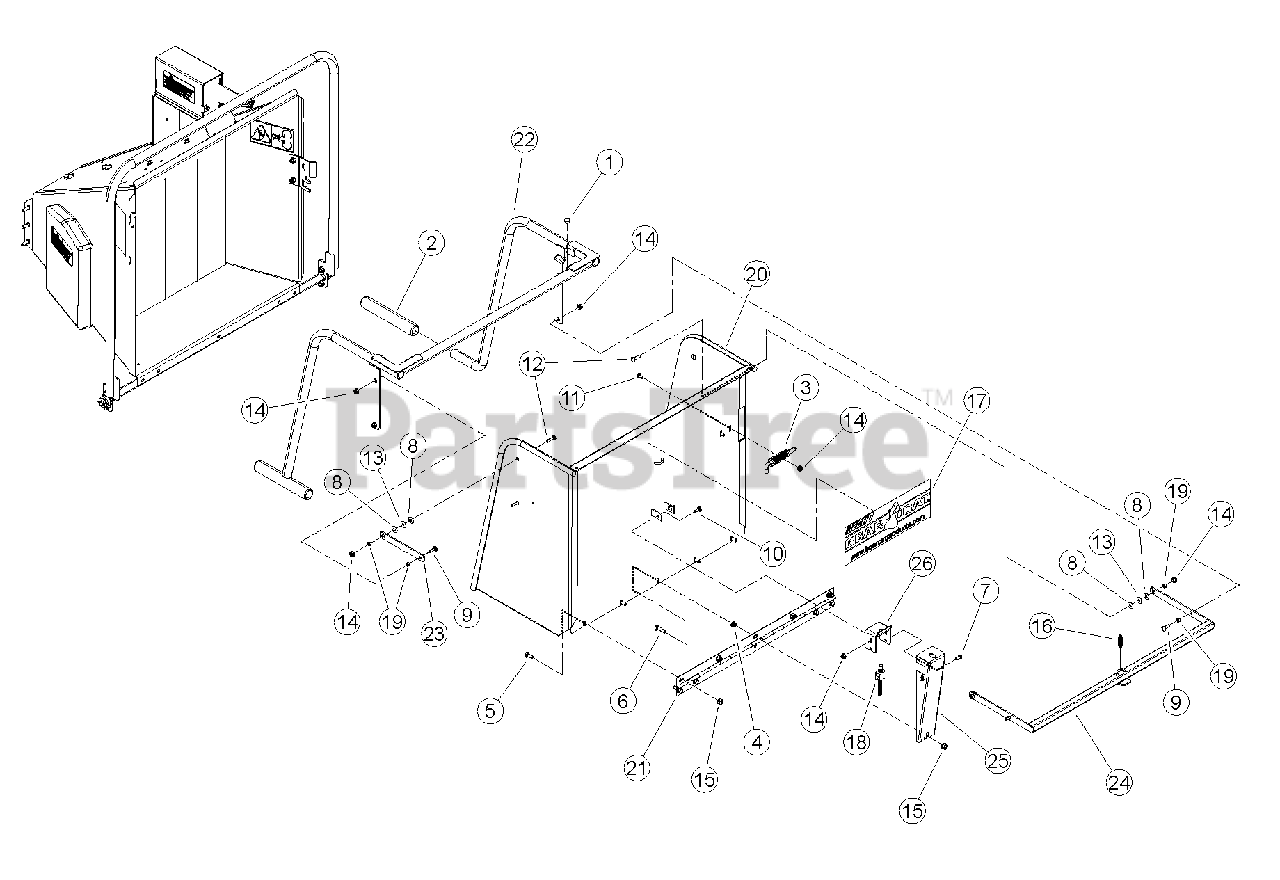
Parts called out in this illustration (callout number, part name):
1	BUMPER, RUBBER
2	GRIP, 1.219 X 10.00
3	LATCH, RH HINGE
4	NUT, 3/8" SERRATED FLANGE NC ZP
5	BOLT, 3/8 X 1" GR5 CRG NC ZP
6	BOLT, 3/8 X 1-1/2" GR5 CRG NC ZP
7	SCREW, 11/32 X 7/8 HWH AB THREAD ZP
8	WASHER, 5/16" FLAT ZP
9	BOLT, 5/16 X 1" GR5 CRG ZP
10	BOLT, 5/16 X 7/8" GR5 CRG NC ZP
11	BOLT, 5/16 X 3/4 GR5 CRG NC ZP
12	BOLT, 5/16 X 1-1/4" GR5 CRG ZP
13	WASHER, 5/16" ID 7/8" OD NYLON FLAT
14	NUT, 5/16-18 NYLOCK-FLANGE
15	NUT, 3/8-16 NYLOCK FLANGE
16	SPRING, 1/2 X 2.00 LG,ZP
17	DECAL, BEARCAT WEB
18	SWITCH, MOMENTARY IP67 NORMALLY ON
19	SPACER, IDLER PIVOT
20	WELDMENT, EXTENSION TRAY
21	HINGE, EXTENSION TRAY
22	WELDMENT, KNEEBAR
23	LINK, PARALLEL
24	WELDMENT, KNEEBAR PIVOT
25	SHIELD, KNEEBAR SWITCH
26	BRACKET, SWITCH
